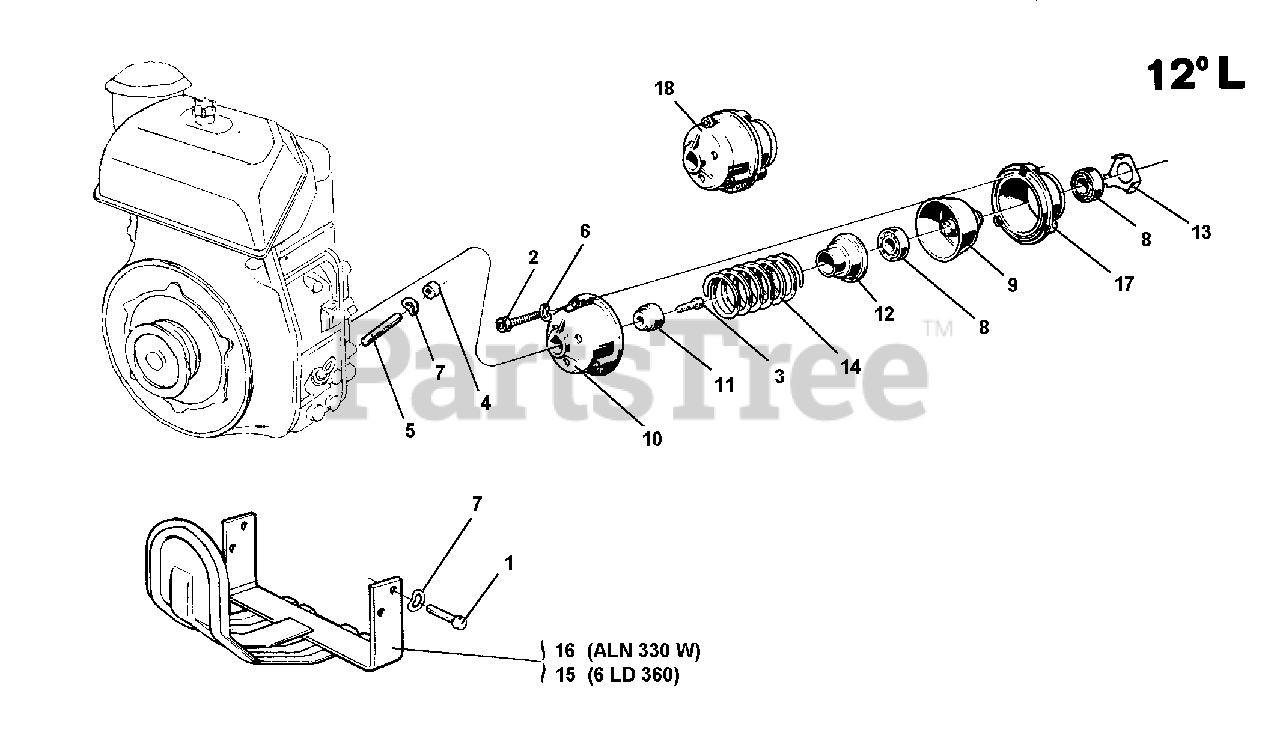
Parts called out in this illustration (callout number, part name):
1	SCREW M8 X 16
2	SCREW TCCEI M6 X 30 UNI 5931
3	SCREW TE CE M8 X 25
5	STUD M8 X 40 X 14 X 14
6	WASHER, LOCK, 6.4
7	WASHER, LOCK 8.4
8	BEARING SKF 17 X 40 X 12 6203 ST
9	LONG CLUTCH CONE
10	LONG CLUTCH BELL
12	BUSH. SPRING HOLDER
13	BEARING PLATE
14	SPRING CLUTCH
15	MOTOR HOOD LDA 520 MF 715 C
16	GUARD, MOWER MOTOR PULLEY
17	LONG CLUTCH RING
18	FITTED LONG CLUTCH
